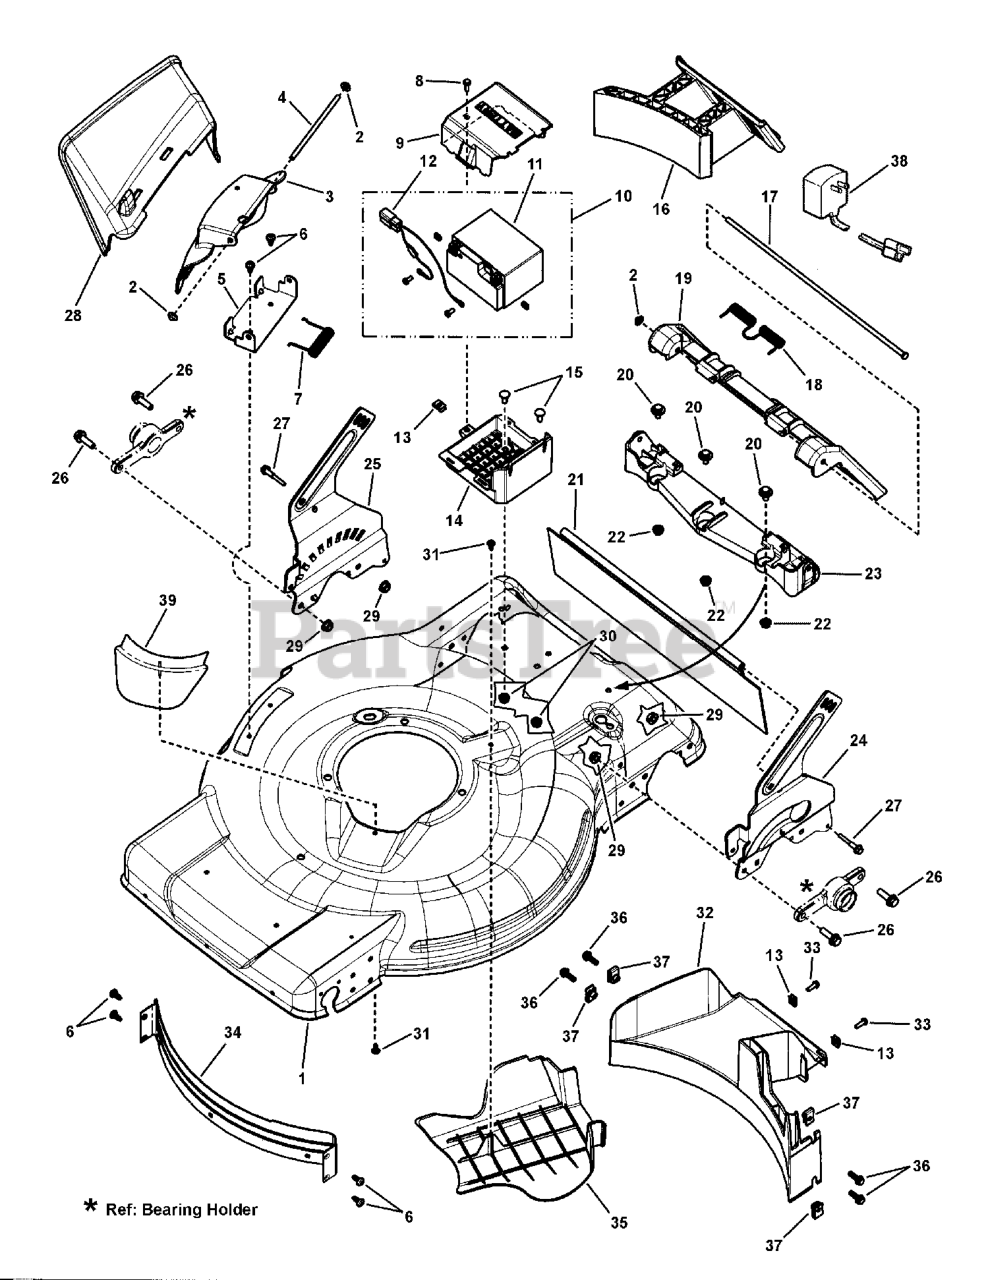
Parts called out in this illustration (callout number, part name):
1	DECK, 22", RWD, ES, DEERE
2	PUSHNUT, 1/4
3	COVER, MULCHING
4	ROD, PIVOT
5	BRACKET, CHUTE
6	TORX ST, 1/4-20 X .550
7	SPRING, TORSION, CHUTE
8	HWFST,10C X 5/8
9	TOP, BATTERY BOX, WBM
10	ASSY, BATTERY W/HARNESS
11	SEALED LEAD ACID BATTERY, 12V
12	HARNESS, BATTERY
13	NUT, RETAINER SPEED #10C W/EXT
14	BOTTOM, BATTERY BOX, WBM
15	FHSNB, 1/4-20X5/8
16	PLUG, MULCHING, 22" DECK
17	ROD, PIVOT, REAR DOOR
18	SPRING, TORSION, REAR DOOR
19	REAR DISCHARGE DOOR
20	HHSTS, 1/4-20 x 5/8"
21	GUARD, REAR 22"
22	HFLN, 1/4-20
23	REAR DISCHARGE DOOR HINGE
24	BRKT, REAR WHEEL, LH, QUICK ADJUST
25	BRKT, REAR WHEEL, RH, QUICK ADJUST
26	HFLB, 5/16-18 X 1 YZ
27	BOLT, DRAG SHIELD, 1/4 - 20 X 1.5
28	CHUTE, SIDE DISCHARGE, WBM, 22"
29	FLN, 5/16-18 YZ
30	HFLN, 1/4-20
31	SCREW, ROUND WASHER HEAD TORX, HI-LO
32	REAR, BAFFLE REAR WHEEL DRIVE WBM
33	HWFST, 10C X 5/8
34	BAFFLE, FRONT
35	COVER, BELT DRIVE, REAR
36	HFLB, 1/4-20X3/4
37	U-NUT, 1/4-20
38	CHARGER, Battery (120 Volt; 60 Hertz)
39	SHIELD, DEBRIS, FRONT
